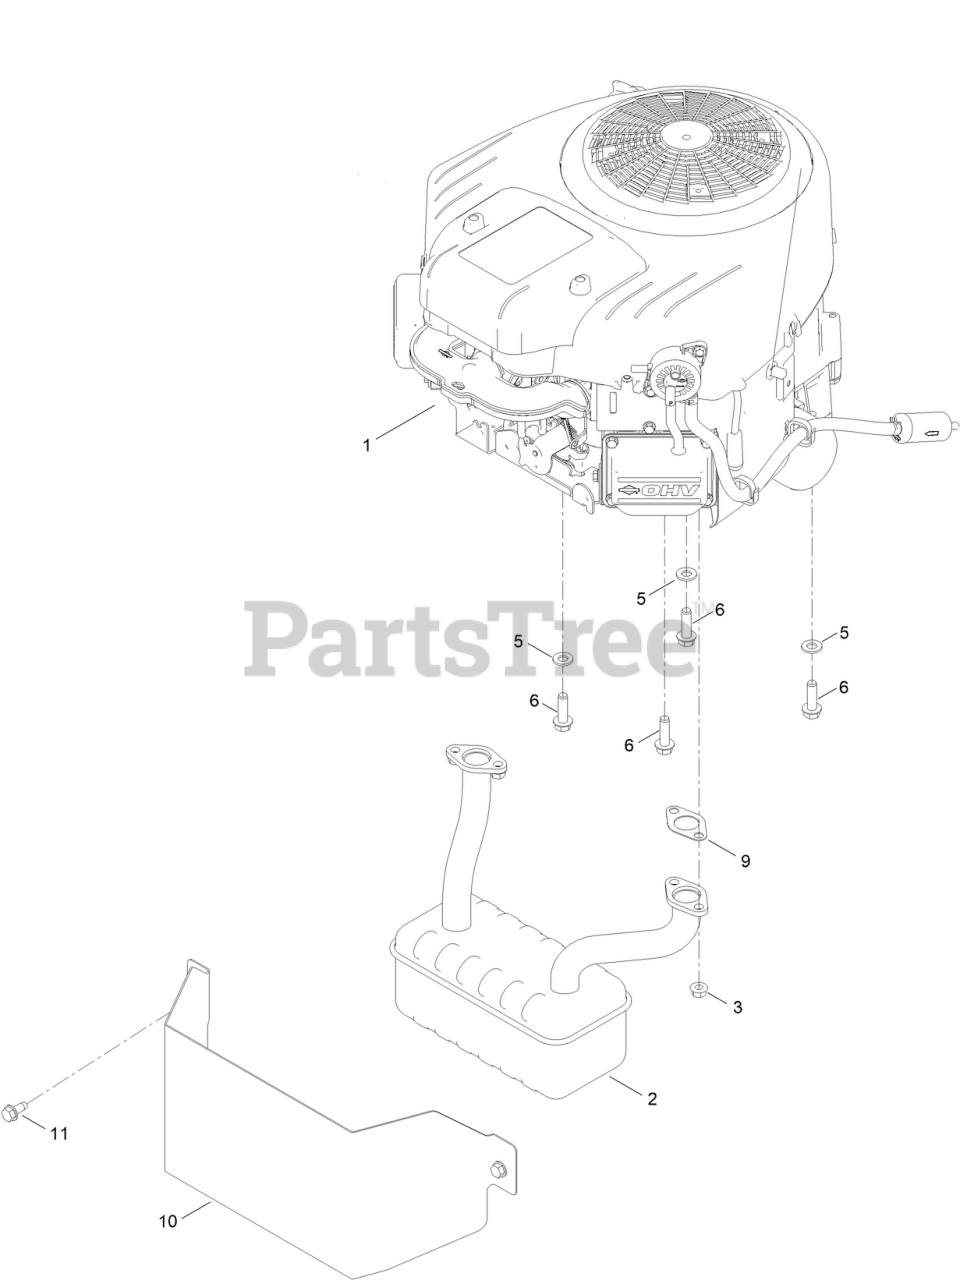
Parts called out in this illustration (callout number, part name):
1	ENGINE - BS EXI
2	MUFFLER
3	NUT-HF
5	WASHER-FLAT
6	SCREW-HWH, THD ROLL
9	GASKET-EXHAUST, BRIGGS TWIN
10	HEAT SHIELD - MUFFLER
11	SCREW-HWHTF
